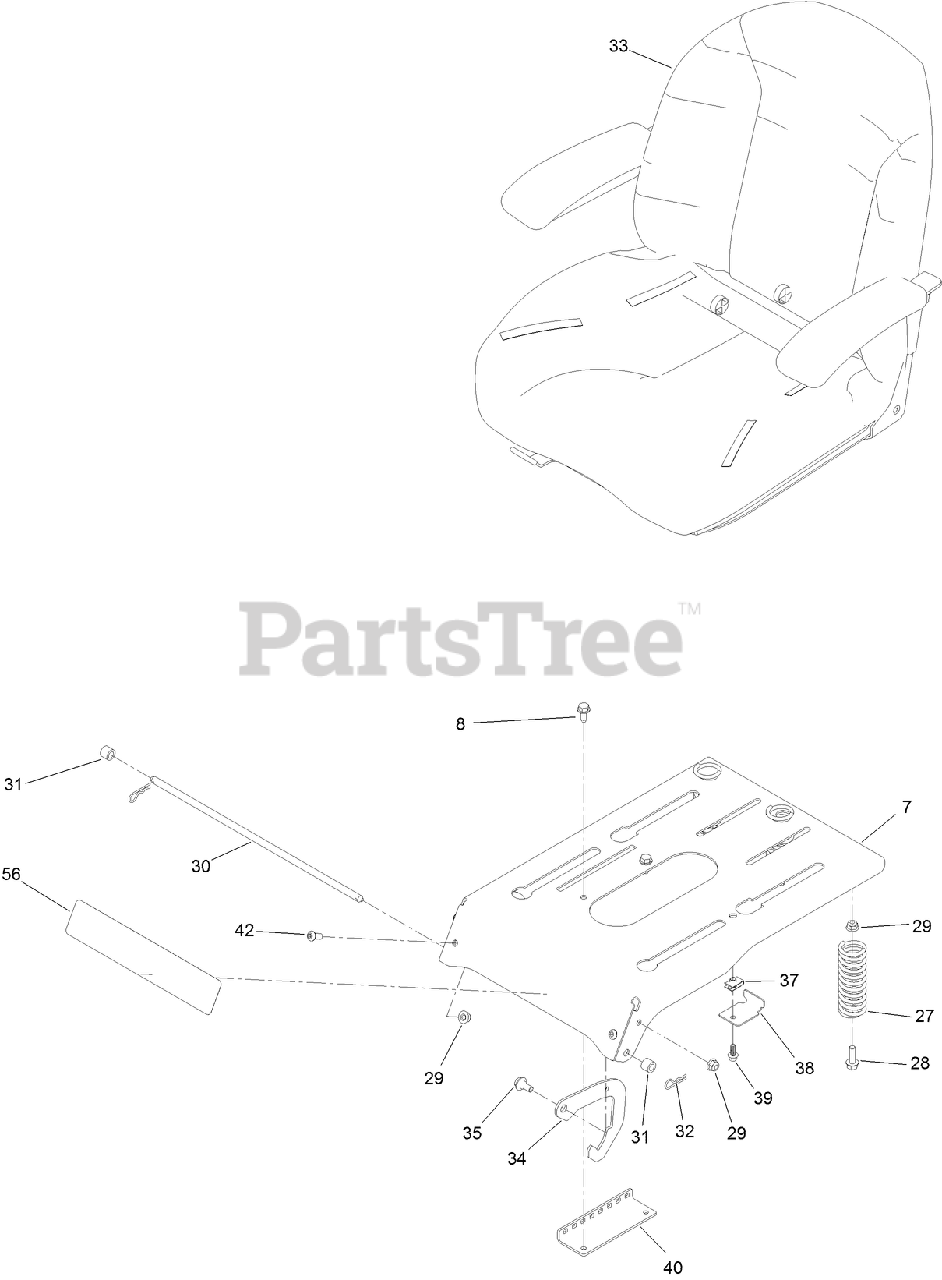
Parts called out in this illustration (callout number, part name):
7	PAN-SEAT, DELUXE
8	SCREW-HWHTF
27	SPRING-COMPRESSION
28	SCREW-HHF
29	NUT-HF, NI
30	ROD-STOP
31	BUSHING-LEVER, LIFT
32	PIN-COTTER
33	SEAT ASM
34	LATCH-SEAT
35	SCREW-SHOULDER
38	BRACKET-STOP, SEAT
39	SCREW-HHF
40	BRACKET-LATCH, SEAT
42	SCREW-HSBH
56	DECAL-TIMECUTTER HD
